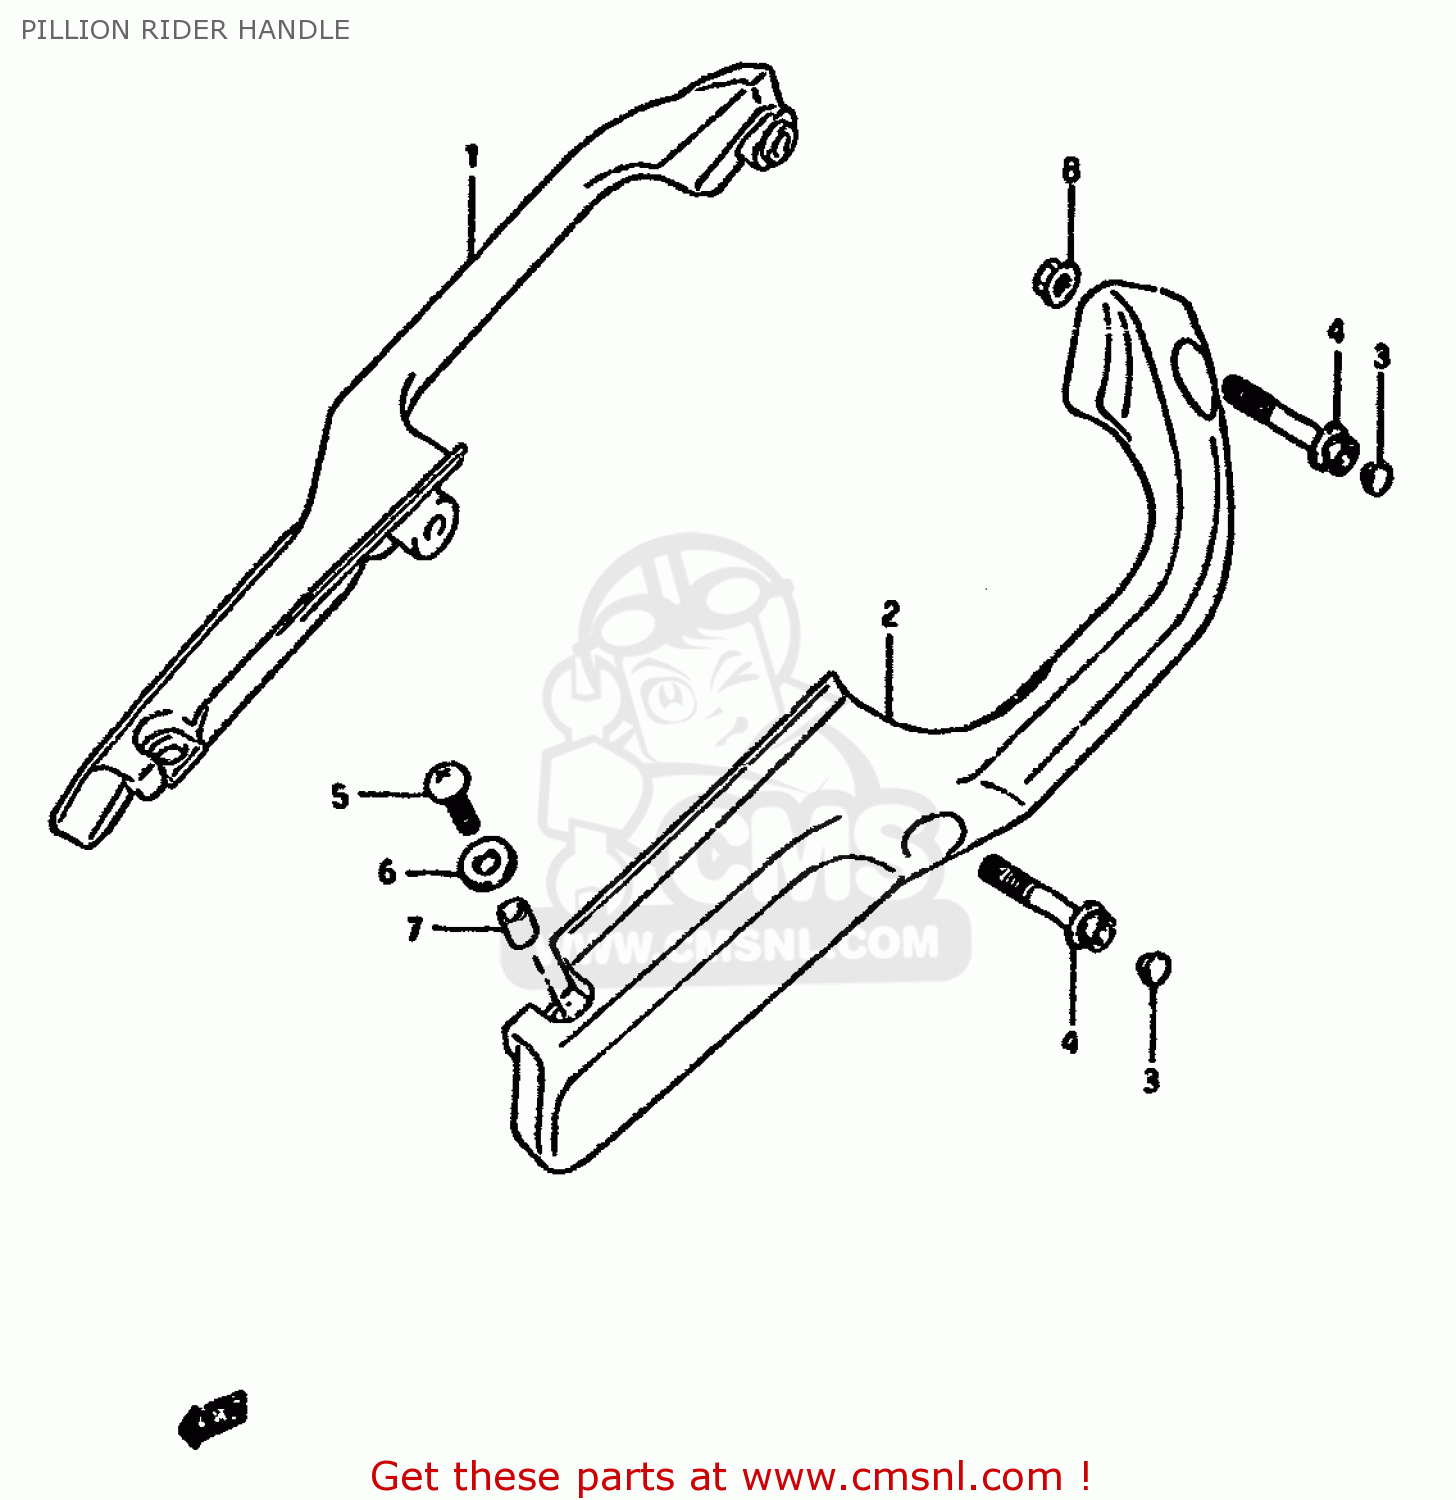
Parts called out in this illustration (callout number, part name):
1	HANDLE,PILLION RIDER,RIGHT
2	HANDLE,PILLION RIDER,LEFT
3	HANDLE,PILLION RIDER
4	BOLT
5	SCREW(6X20)
6	WASHER
7	SPACER (6X9X8)
8	NUT
